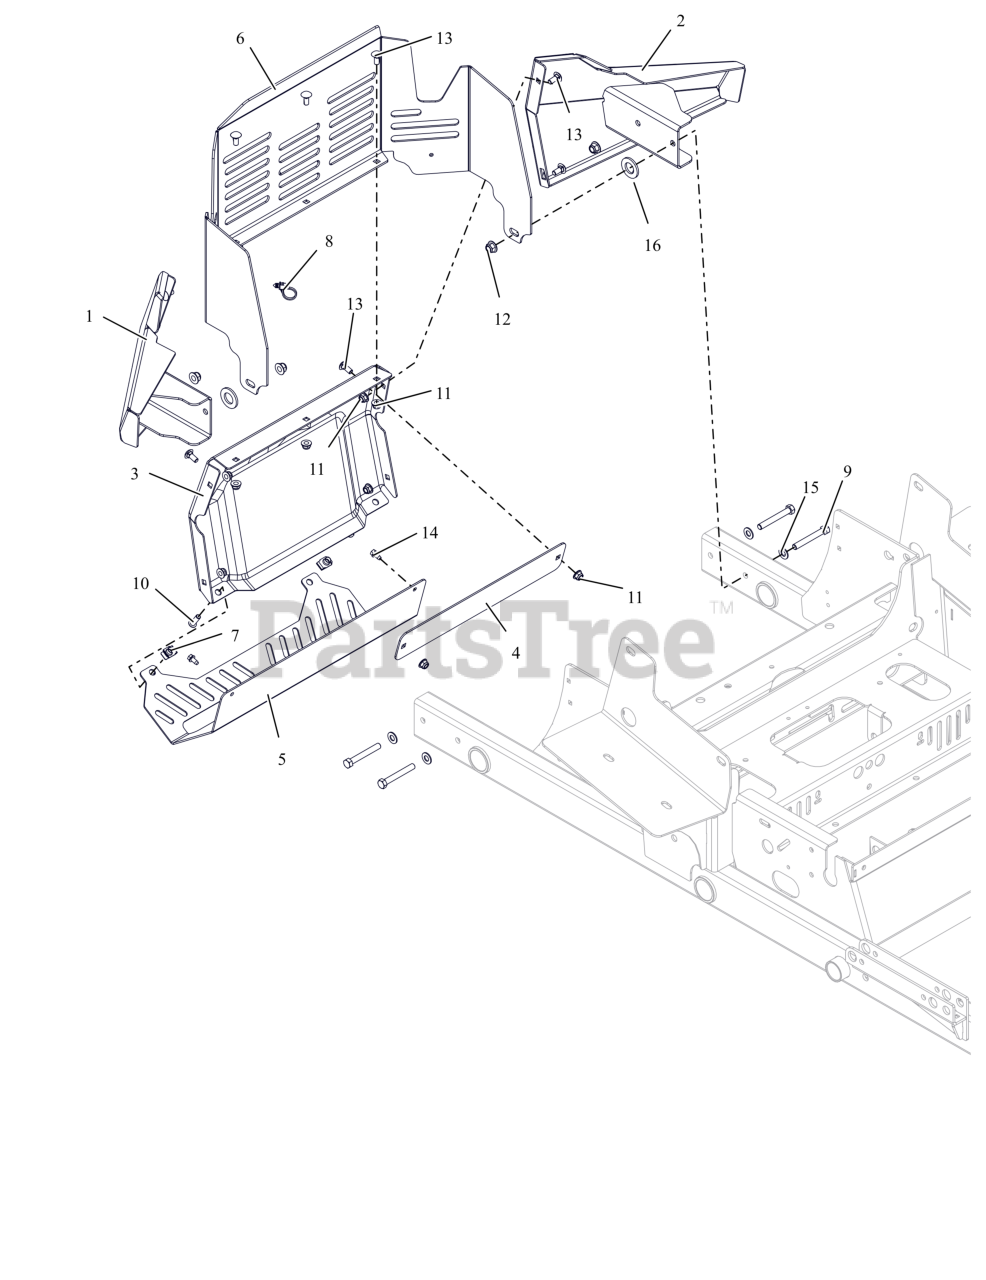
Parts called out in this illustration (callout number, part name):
1	WMT,RH REAR BMPR WING W/DECAL
2	WMT,LH REAR BMPR WING W/DECAL
3	PT200/400 REAR BUMPER - BLACK
4	BACKER PLATE - RED
5	PT200/400 MUFFLER GUARD - BLK
6	PT200 ENGINE GUARD - RED
7	NUT-CLIP RETAINER 5/16-18X.56
8	CABLE TIE W/ TREE (.25 HOLE)
9	BLT, HEX .38-16X2.75 G5 ZCC
10	BLT,SHCS-BTN .31-18X1.00 ZCC
11	NUT,NYL-FLG .31-18 GF ZCC
12	NUT,NYL-FLG .38-16 GF ZCC
13	BLT,RHSN .31-18X.75 G5 ZCC
14	SCR-TAP .25-20X.50 HWH ZCC
15	WSHR,FLT .406X.812X.065 ZCC
16	WSHR-FL-STL 0.812X1.469X0.134 ZCC
